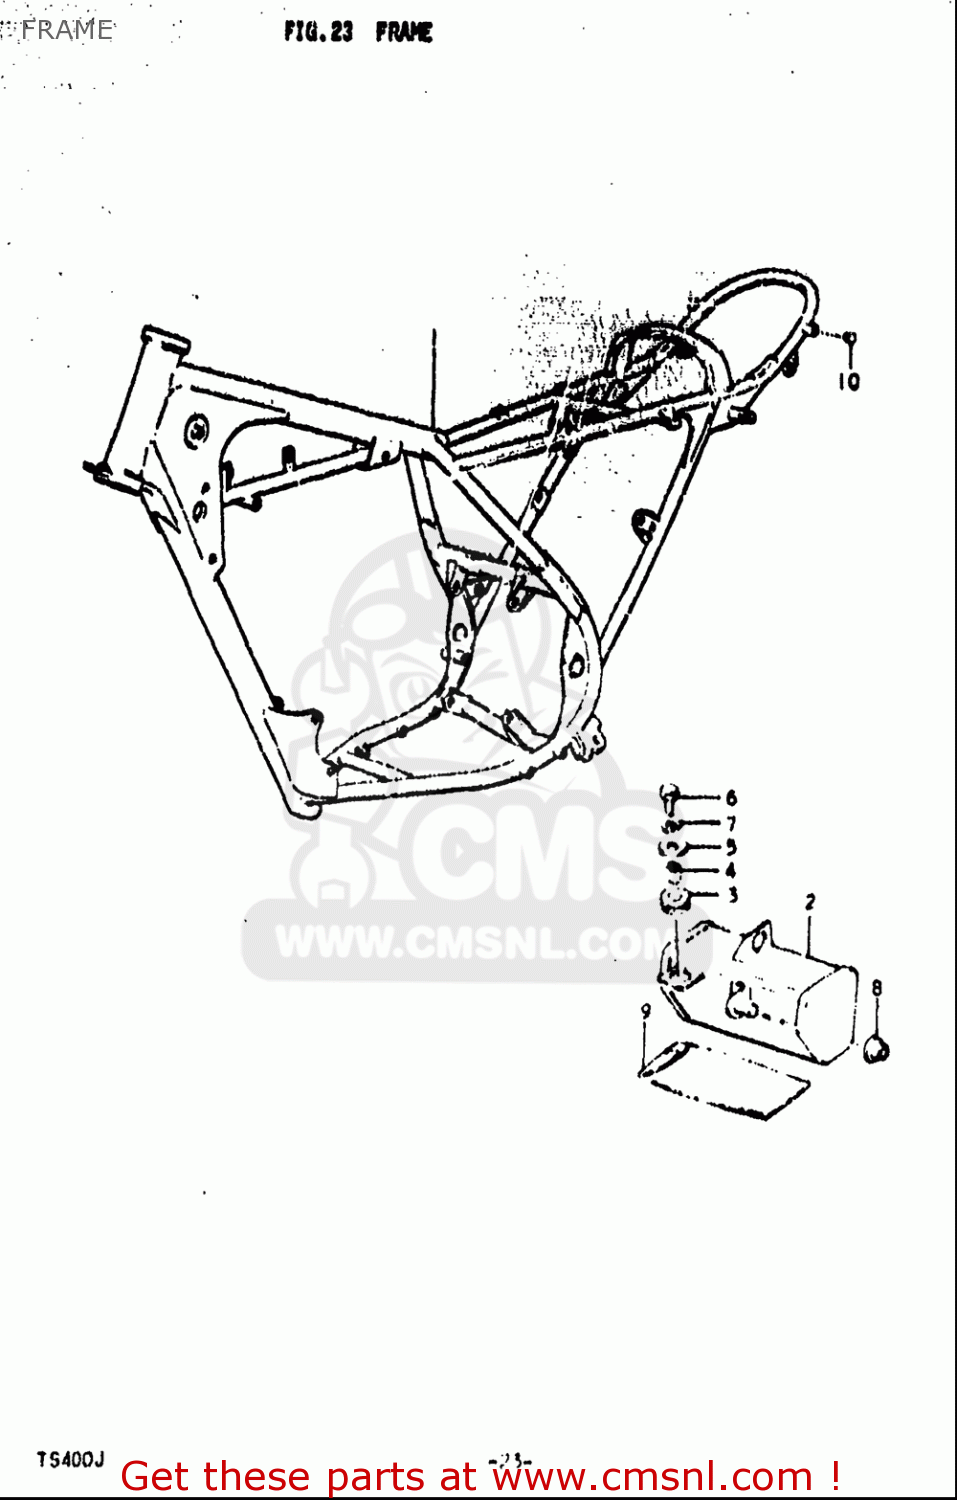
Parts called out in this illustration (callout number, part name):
3	CUSHION
5	WASHER(6.5X20X1.2)
6	BOLT(6X20)
7	WASHER,LOCK
10	CAP(OD:14)
